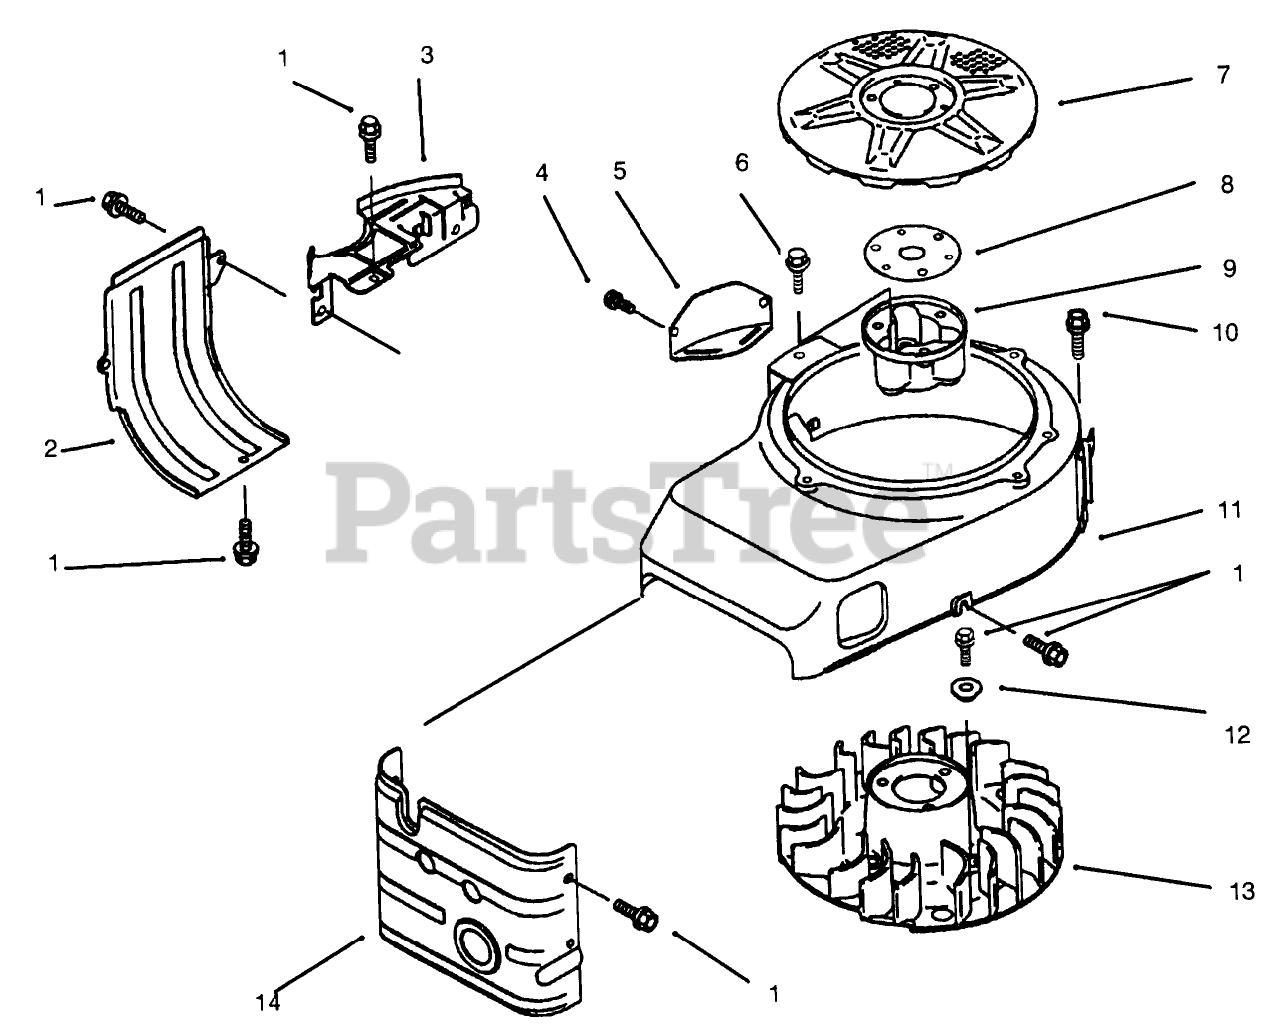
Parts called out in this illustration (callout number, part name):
1	Bolt-Flanged (6X10)
2	Shroud
3	Fan Housing
4	Screw
5	Cover
6	Bolt-Flange
7	Screen
8	Shim T-1.20
9	Bracket
10	Bolt-Flanged (6X14)
11	Housing-Fan
12	Collar
13	Fan
14	Shroud
